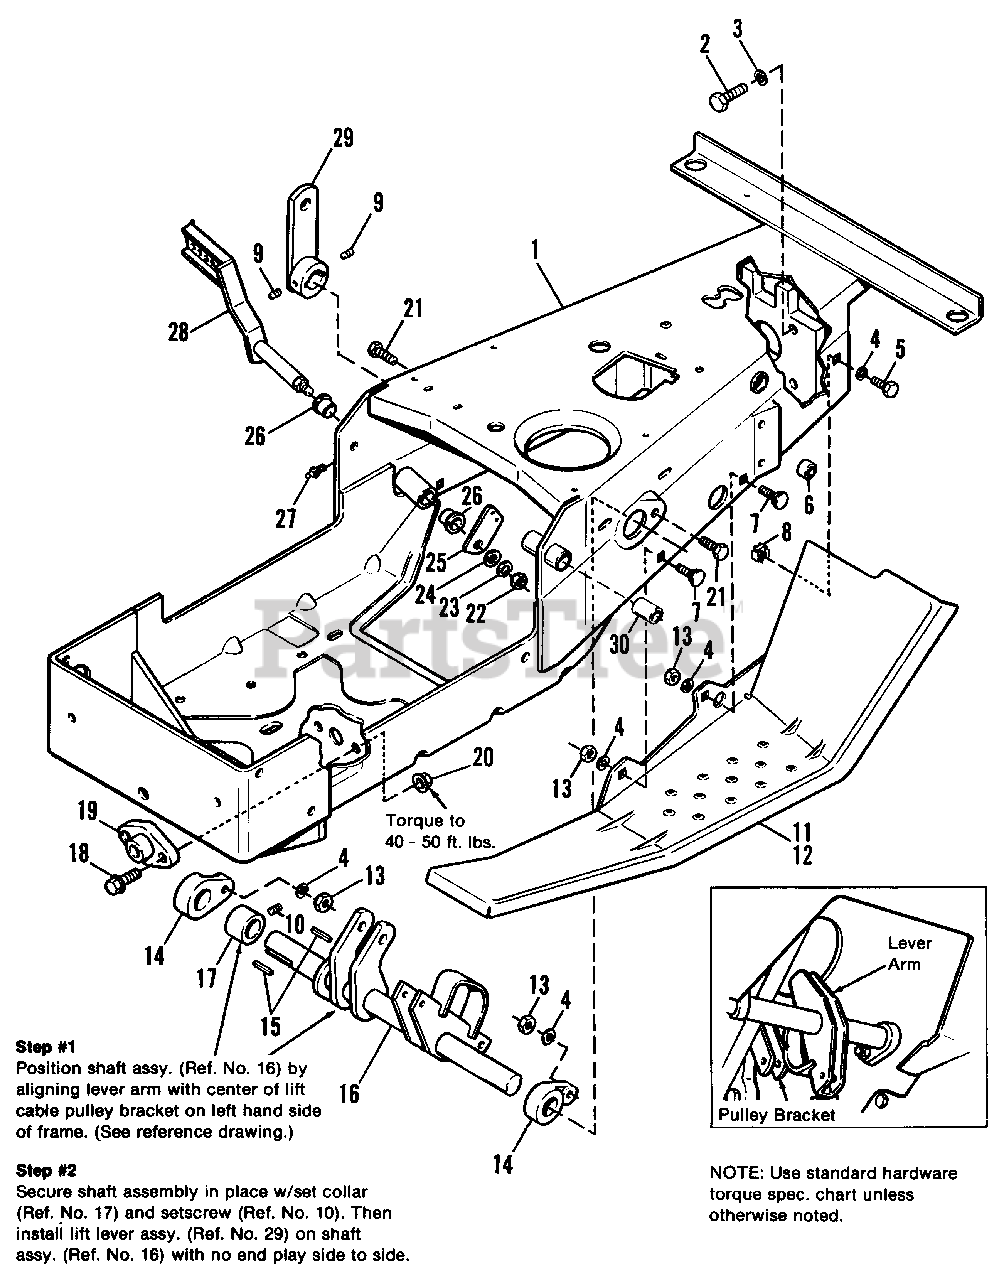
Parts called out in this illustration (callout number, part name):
1	FRAME ASSY., w/Bushings
2	CAPSCREW, Hex Hd., 7/16-14 x 1-1/2
3	LOCKWASHER, 7/16
4	LOCKWASHER, 5/16
5	CAPSCREW, Hex Hd., 5/16-18 x 3/4
7	CARRIAGE BOLT, 5/16-18 x 3/4
8	NUT, Speed, 5/16-18
9	SETSCREW, 5/16-18 x 1/4
10	SETSCREW, 5/16-18 x 1/2
11	FOOTREST, L.H.
12	FOOTREST, R.H.
13	NUT, Hex, Full, 5/16-18
14	BEARING, Lift Lever
16	SHAFT ASSY., Lift (Hydro Lift)
17	COLLAR, Set
18	SCREW, Hex, Flange, Whiz, 3/8-16 x 1-1/4
19	BEARING, Pivot
20	LOCKNUT, Hex, Flange, 3/8-16
21	CAPSCREW, Hex Hd., 5/16-18 x 1-1/4
22	NUT, Hex, Full, 3/8-16
23	LOCKWASHER, 3/8
24	WASHER, Plain, 3/8
25	ARM, Foot Pedal
27	FITTING, Grease
28	PEDAL ASSY., Foot
29	LEVER ASSY., Front Lift
30	BEARING, lnterim Pinion
